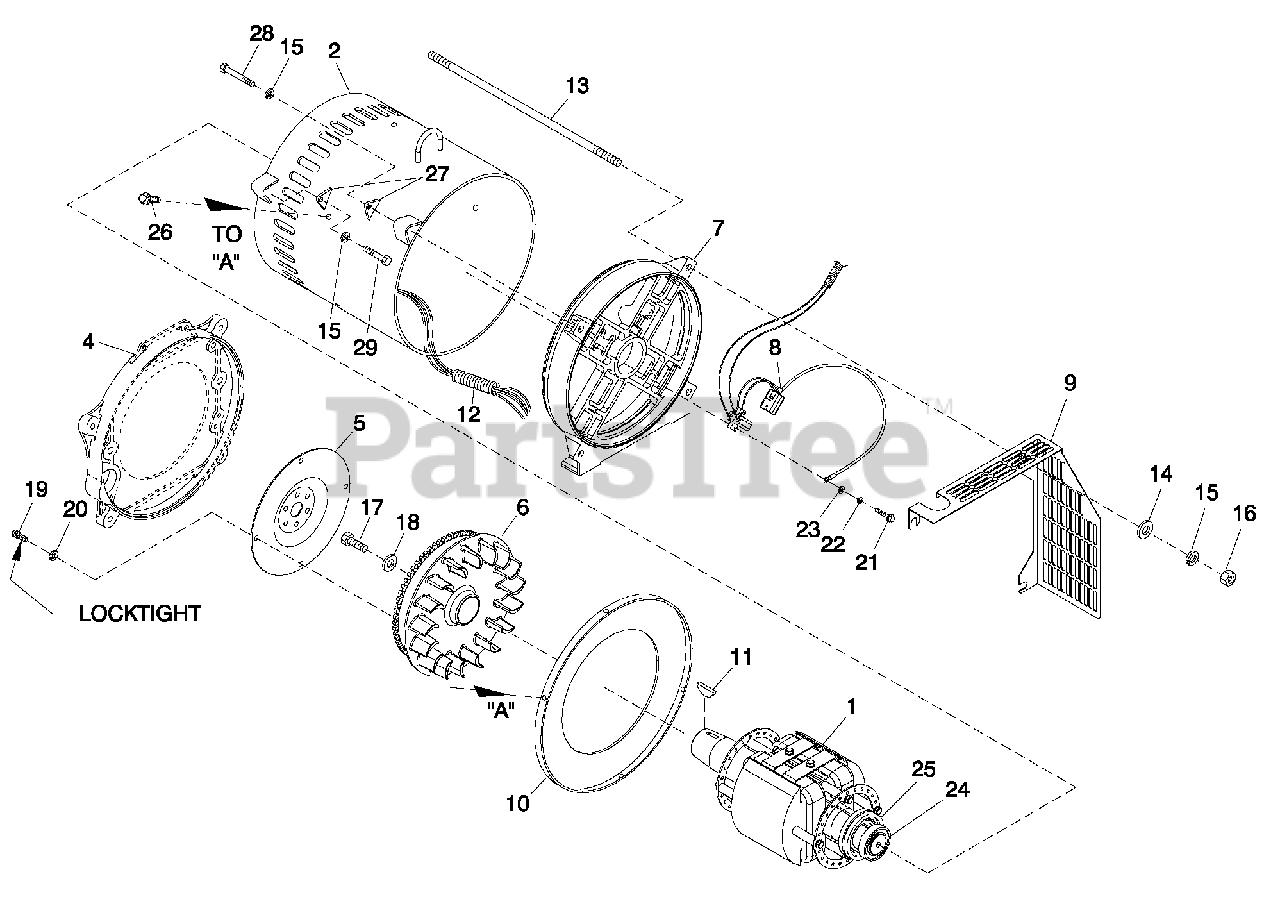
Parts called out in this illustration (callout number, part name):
1	RTR-2390-60KD2 CPL
2	ASSY STR 2390 60AD2 CPL
4	ENGINE ADAPTER
5	FLEXPLATE
6	ASSY FLYWHEEL CPL W/40MM FAN B
7	REAR BEARING CARRIER 390/DRCT
8	ASSY BRUSH HOLDER 390/HSB
9	GUARD REAR BEARING CARRIER CPL
10	RING PRESSURE 390 STATOR CAN
11	KEY WOODRUFF (E
12	CONDUIT FLEX 1-1/4" (30" LG)
13	STUD M14-2.0 X 615 G5 ZINC (70KW)
14	WASHER FLAT M14
15	WASHER LOCK M14
16	NUTHEXM14-2.0 G8 YEL CHR
17	SCREW HHC M16-2.0X 45 G8.8
18	SPACER .69 X 2.75 X .37 ST/ZNC
19	SCREW SHC M10-1.5X 16 G10.9
20	WASHER LOCK M10
21	SCREW HHTT M4-0.7X25BP
22	WASHER LOCK (8-M4
23	WASHER FLAT (8 ZINC
24	BALL BEARING-45 MM
25	SLIP RING MACHINED
26	SCREW 1/4-20 X 5/8" TAPTITE SS
27	WASHER 390 SAE ALT.
28	SCREW HHC M14-2.0 X 140 G8.8
29	SCREW HHC M14-2.0 X 100 G 8.8
